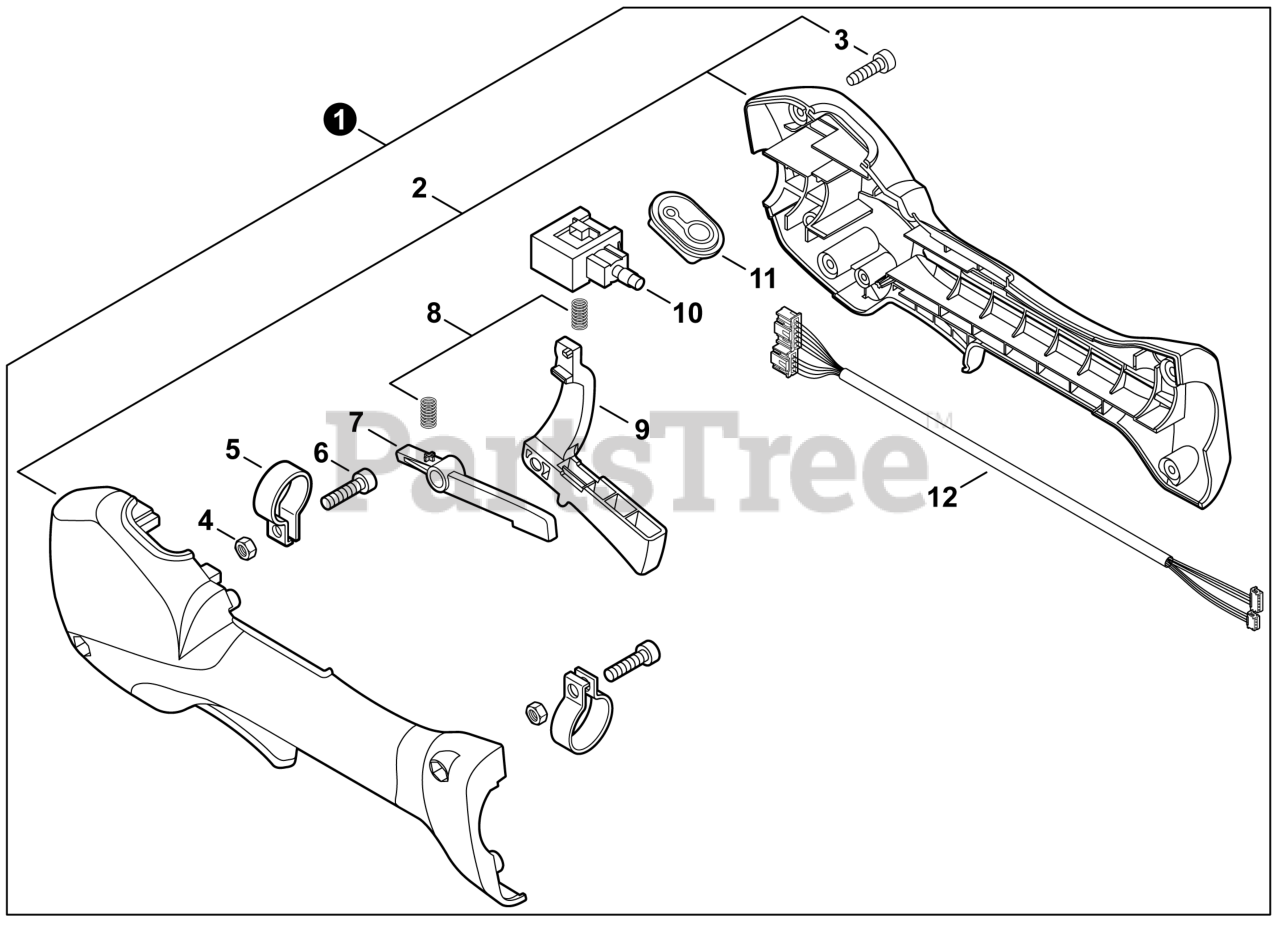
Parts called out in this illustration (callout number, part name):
1	CONTROL HANDLE ASSY
2	CONTROL HANDLE SET
3	BOLT, TORX 4x16
6	BOLT, TORX 5x16
7	LOCKOUT, THROTTLE
8	SPRING, COIL
9	THROTTLE TRIGGER
10	SWITCH, SPEED CONTROL
11	SWITCH, ON-OFF
12	LEAD - IGNITION
